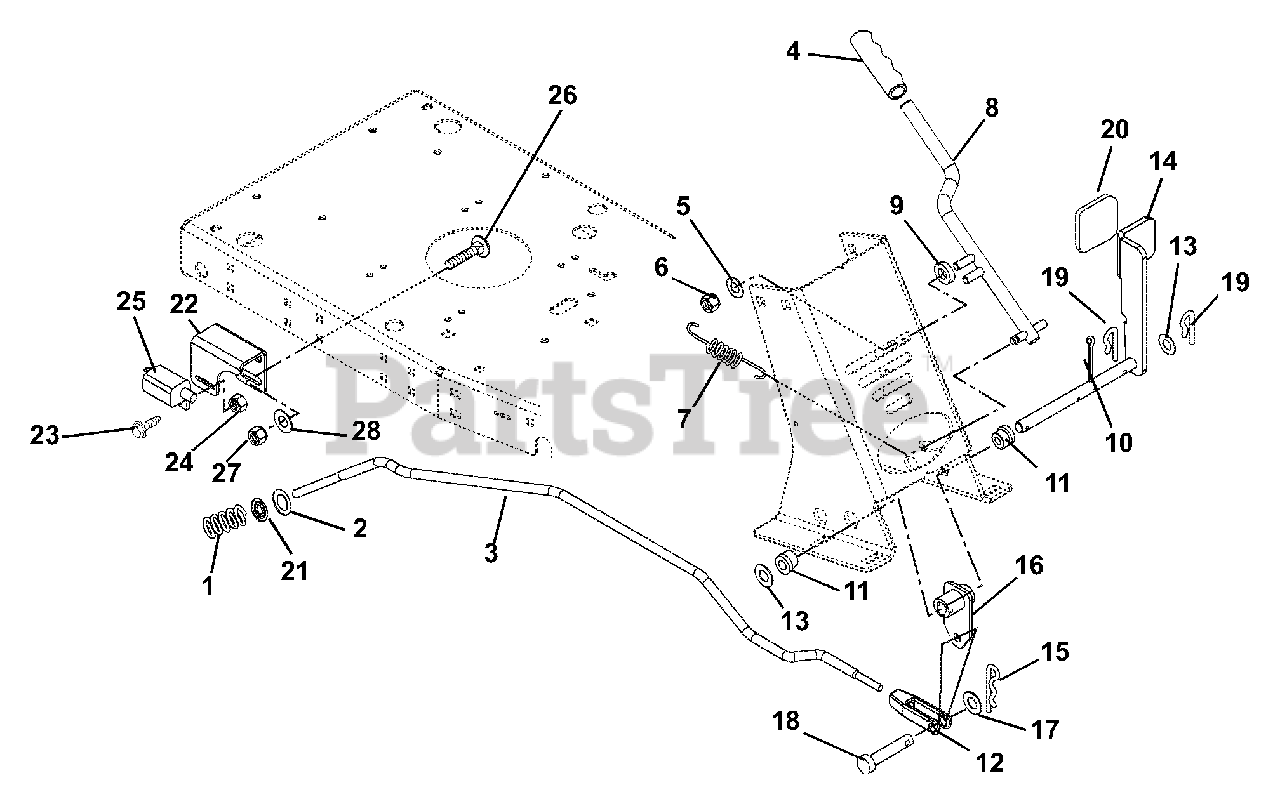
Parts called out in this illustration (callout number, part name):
1	Spring, Compression .080 x .52 x 2.90
2	Washer, Flat Steel .33 x 2.125 x .098
3	Rod, Brake
5	Washer, Flat Steel .38 x .875 x .083
6	Nut, Locking Top Flange .38-16
7	Spring, Tension .048 x .44 x 2.12
8	Weldment, Parking Brake
9	Bushing, Flange .406 x .88 x .27 x .140 Grade 2
10	Pin, Cotter .12 x 1.00 Extended Prong Square Cut
11	Bushing, Flange .515 x .75 x .745 x 1.00 Nylon
12	Yoke, .312-24 x 2.25
13	Washer, Flat Steel .505 x 1.00 x .062
14	Weldment, Brake Pedal
15	Pin, Hair
16	Brake Rod Arm and Hub
17	Washer, Flat Steel .38 x .87 x .179
18	Pin, Clevis .312 x .822
19	Clip, Spring
20	Grip, Pedal
21	Nut-Push .312
22	Bracket, Switch Mount
23	Screw, Machine 10-24 x .75 Hex Washer Head
24	Nut, Locking Nylon 10-24 with Insert
25	Switch, Interlock
26	Bolt, Round Head Square Neck .38-16 x 1.00 Grade 5
27	Nut, Locking Nylon .38-16
28	Washer, Flat Steel .406 x .812 x .065
